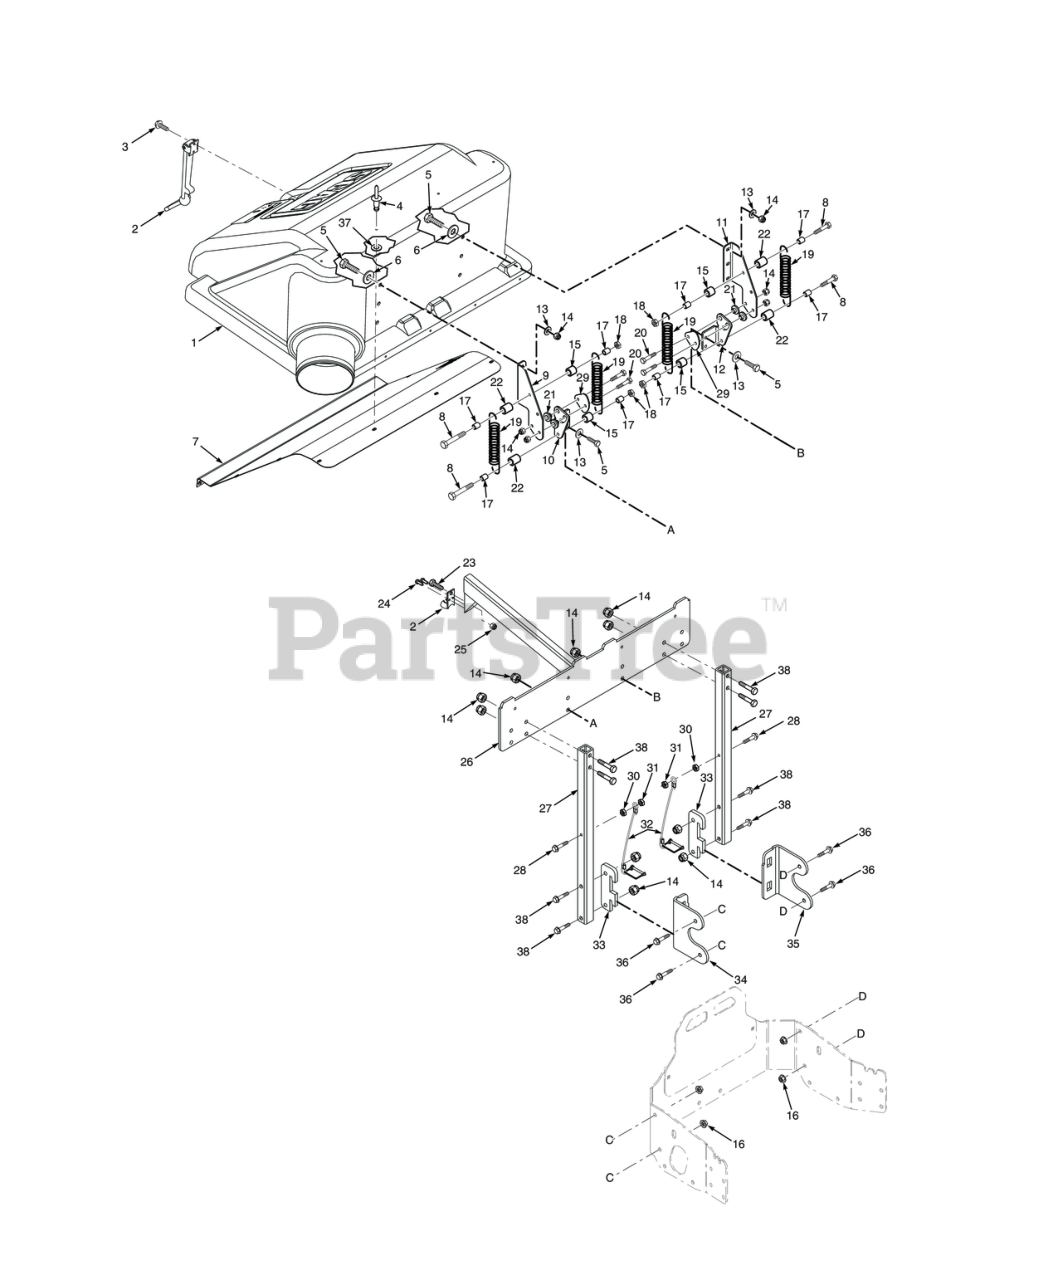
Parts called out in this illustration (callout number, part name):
1	Hood Assembly
2	Latch, Hopper
3	Screw, #10-32 x 3/4"
4	Pop Rivet, 3/16 x .652"
5	Bolt, Hex Head 3/8-16 x 1-1/4", Kawasaki FX / FS
6	Flatwasher, 3/8-.406 x 1-1-1/2 x 7 Gauge
7	Screen, GC Hood
8	Bolt, Hex Head 3/8-16 x 4.00
9	Hinge, Upper RH
10	Hinge, Lower RH
11	Hinge, Upper LH
12	Hinge, Lower LH
13	Flatwasher, 3/8" Special (.391 x .938 x .105)
14	HEX NUT, ELASTIC STOP LOCK, 3/8-16
15	SPACER, J-PULL ROD
16	NUT, 3/8-16 SERRATED FLANGE HEX HEAD
17	Spacer, Deck Assist
18	Bolt, Hex Head 3/8-16 x 1" Ser. Flg.
19	Spring, Hood Hinge
20	Bolt, Hex Head, 3/8-16 x 1-1/2"
21	Bushing, Hopper Pivot
22	Spacer
23	BOLT, SERRATED FLANGE HEX HEAD 5/16-18 X 3/4"
24	Rivot, 3/16 x .402 POP
25	HEX NUT, ELASTIC STOP LOCK, 5/16-18
26	Frame Weldment, Bag Support
27	Tube, Grass Catcher Mount
28	Bolt, Hex Head 1/4-20 x 0.63"
29	Guard, GC Hinge
30	NUT, 1/4-20 SERRATED FLANGE HEX HEAD
31	Bolt, Hex Hd. 1/2-13 x 9-1/2"
32	Snap Pin Assembly w/Lanyard
33	Latch, GC-SFZ
34	Bracket, GC Mount RH
35	Bracket, GC Mount LH
36	Bolt, Hex Head, 3/8-16 x 1 Gr. 5
37	Flatwasher, 3/16 (.196 x .469 x .048)
38	Bolt, Hex Head 3/8-16 x 2-1/4" - 61"
